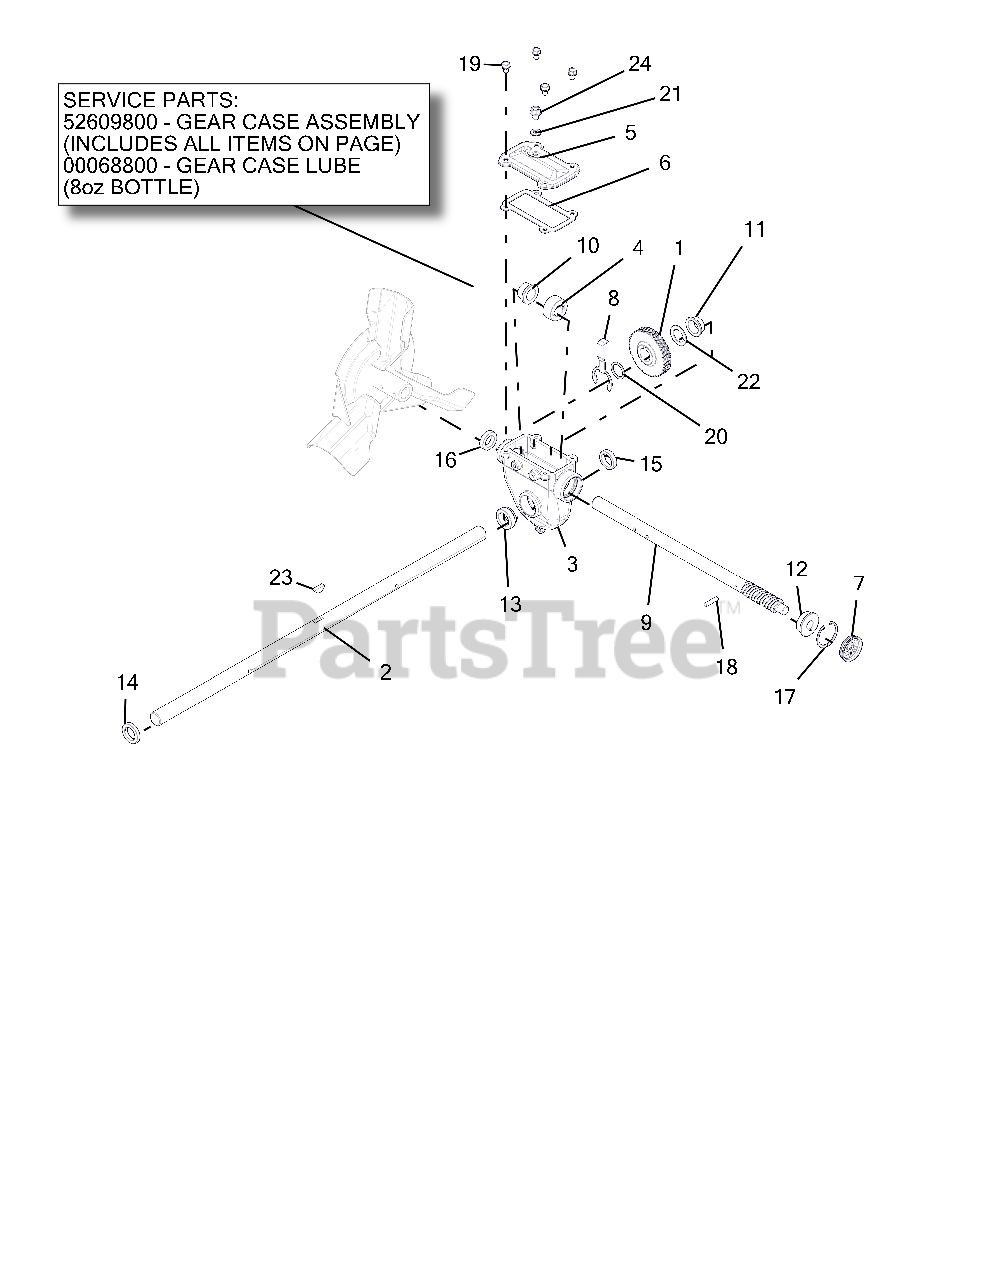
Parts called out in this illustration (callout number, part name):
1	WORM GEAR
2	SHAFT, RAKE-32"
3	GEARCASE, LARGE MACHINED
4	THRUST COLLAR, .875"ID SLIPFIT
5	COVER, TOP - LARGE IRON
6	GASKET, TOP - LARGE GEARCASE
7	COVER, GEAR CASE 1.75"
8	BUSHING RETAINER, LARGE
9	SHAFT, WORM - PRO
10	BSHG-FLG .879X1.128X.75X1.45
11	BSHG-FLG 1.006X1.128X.555X1.45
12	BSHG-FLG .628X1.503X.58X1.725
13	BSHG-FLG LARGE, RIGHT
14	SEAL-OIL .999X1.500X.250 TBC29
15	SEAL-OIL .999X1.375X.312 TBC29
16	SEAL-OIL .873X1.375X.312 TBC29
17	RG-RTNG-INT 1.750X.062
18	PIN-STR .250X1.12 6150
19	BOLT, SEMS .31-18X.50 GR5 YWZC
20	WSHR-FL-STL 1.010X1.250X.068YZ
21	WSHR-BND-SEAL .38X.75X.11 GALV
22	WSHR-FL-STL 1.010X1.505X.062YZ
23	KEY-WDRF .25X.875 HRD #A
24	@SCR-ROLOK .38-16X.50 HWH YWZC
25	GEAR CASE, 32" IRON PRO TOP-LD
26	ARIENS L3 LUBE, 8 OZ BOTTLE
